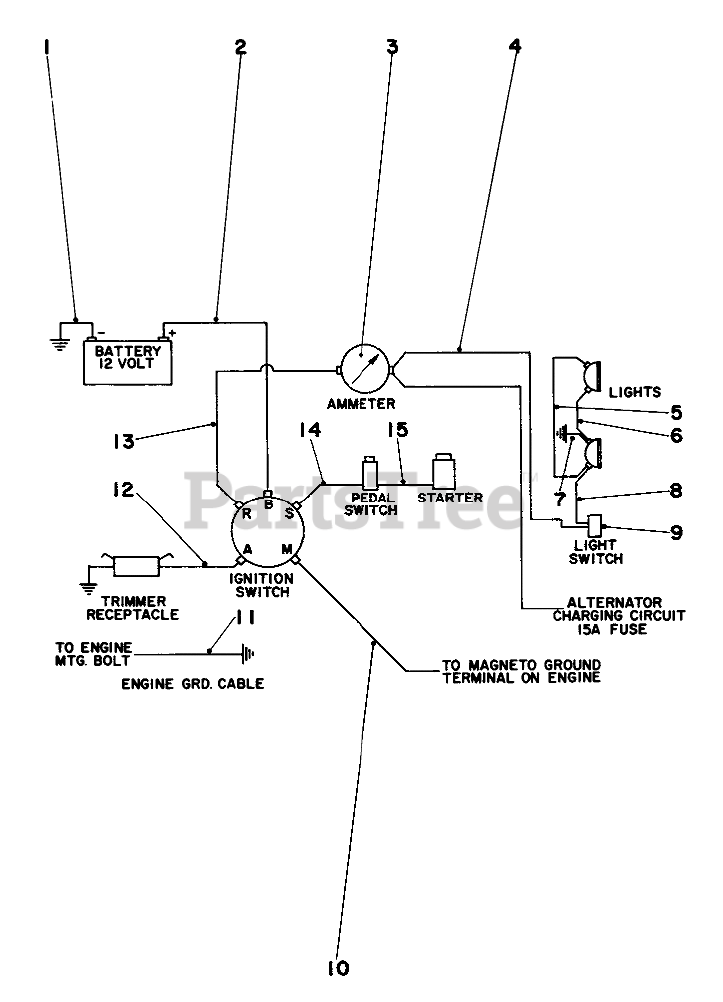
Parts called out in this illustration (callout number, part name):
1	Wire Assembly
2	Wire Assy.
3	Ammeter
5	Wire 960
6	Wire 960
7	Wire Assy.-Red
8	Wire Assy.
9	Light Switch
10	Wire Switch to Battery
11	ENG-GROUND WIRE ASM
12	Wire Assembly
13	Wire Assy. Ammeter to Switch
14	Wire Pedal Switch to Starter Switch
15	Wire Assembly
